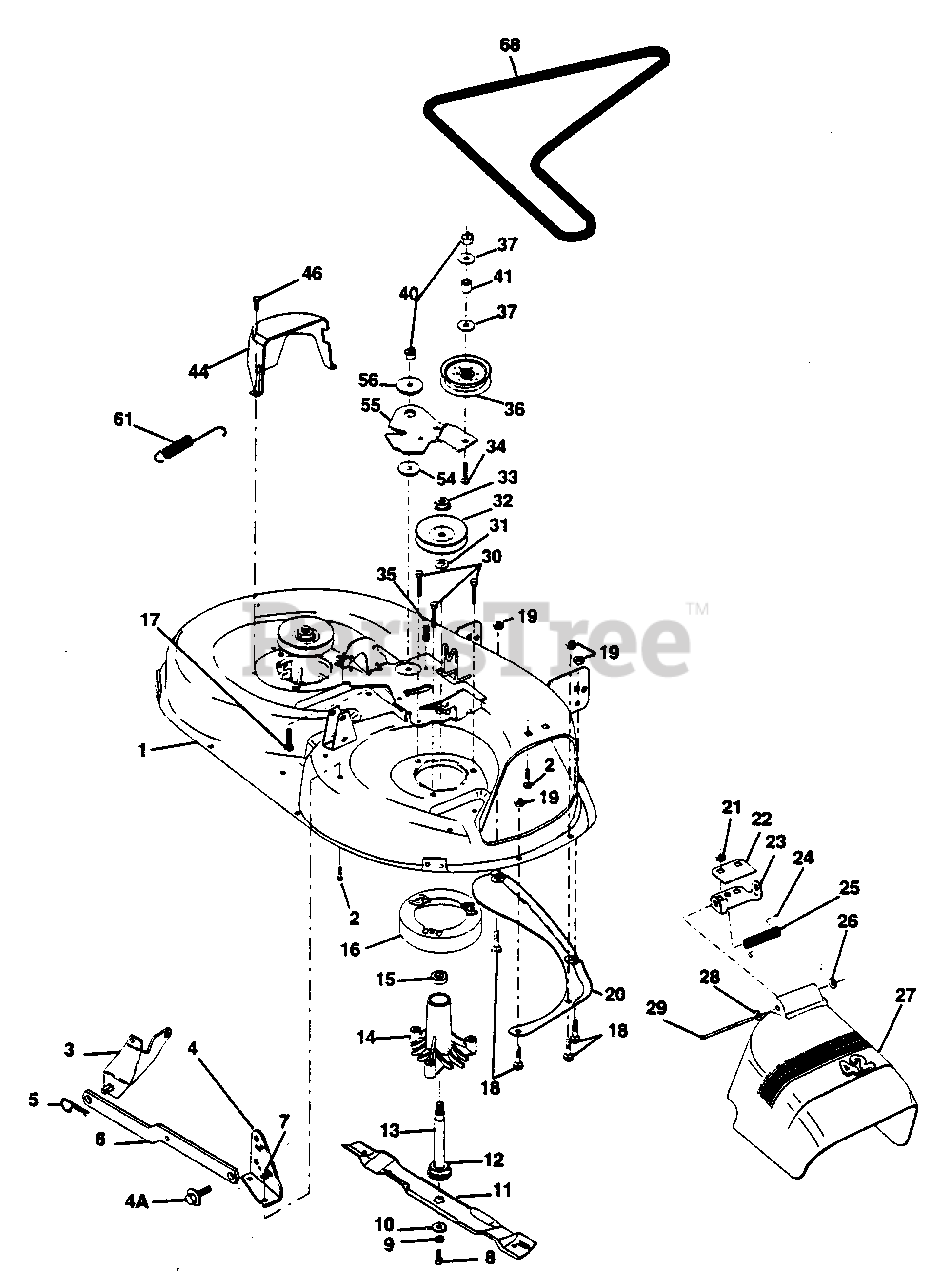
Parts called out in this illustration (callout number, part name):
1	Deck Asm Mower 42" (AYP part number)
2	Bolt Rdhd Sqnk 5/16-18unc X3/4
3	Bracket Asm Fr Sway Bar (AYP part number)
4	Bracket Asm Deck Sway Bar 42" (AYP part number)
5	Retainer Spring (AYP part number)
6	Arm Suspension Rear (AYP part number)
7	Locknut Hex W/Ins 5/16 - 18 (AYP part number)
8	Bolt 3/8-24x1 25 Gr8 Patched (AYP part number)
9	Washer Lock Hvy 3/8 Unplated (AYP part number)
10	Washer Hard Blade Mower Vented (AYP part number)
12	Bearing Ball #6204 (Mandrel) (AYP part number)
13	Shaft Asm W/lower Bearing
14	Housing Mandrel Vented(machd)
15	Bearing Ball Mandrel (AYP part number)
16	Stripper Mower Vented (AYP part number)
17	Bolt Rdhd Sqnk 3/8-16 X 1-1/4
18	Bolt Rdhd Sqnk 5/16-18 X 5/8 (AYP part number)
19	Locknut-hex W/ins 5/16-18unc P (AYP part number)
20	Baffle Vortex 42 (AYP part number)
21	Nut Lock Hx w/Ins 5/16-18 (AYP part number)
22	Stiffener Bracket 42" deck (AYP part number)
23	Bracket Deflector Mower 42" (AYP part number)
24	Cap Sleeve 80x 112 Blk Mower (AYP part number)
25	Spring Torsion Deflector 2 52 (AYP part number)
26	Nut Push Phos & Oil (AYP part number)
27	Shield Deflector Mower 42" Blk" (AYP part number)
28	Washer 11/32 X 5/8 X 16 Ga (AYP part number)
29	Rod Hinge 42" 6 75 Wlg (AYP part number)
30	Screw Thdrol Hex Head (AYP part number)
31	Washer Spacer Mower Vented (AYP part number)
32	Pulley Mandrel 42" (AYP part number)
33	Nut Flg Top Lock Cntr B 9/16
34	Bolt Rdhd 3/8-16uncx1-3/4 Gr5 (AYP part number)
35	Fastner Christmas Tree (AYP part number)
36	Pulley Idler Flat 3 060 (AYP part number)
37	Washer 13/32 X 13/16 X 16 Ga (AYP part number)
40	Nut Lock Hx w/Wsh 3/8-16 Unc (AYP part number)
41	Spacer Spring Stop Idler
44	Guard Mandrel LH Black (AYP part number)
46	Screw Hex Thd Cut 1/4-20x5/8 T (AYP part number)
54	Washer Hardened (AYP part number)
55	Arm Idler 42" mower LT/YT (AYP part number)
56	Spacer Retainer Pm Mower (AYP part number)
61	Spring Ext. Elect. Clutch 38/42"
68	V-Belt Mower 42" 82 625 (AYP part number)
